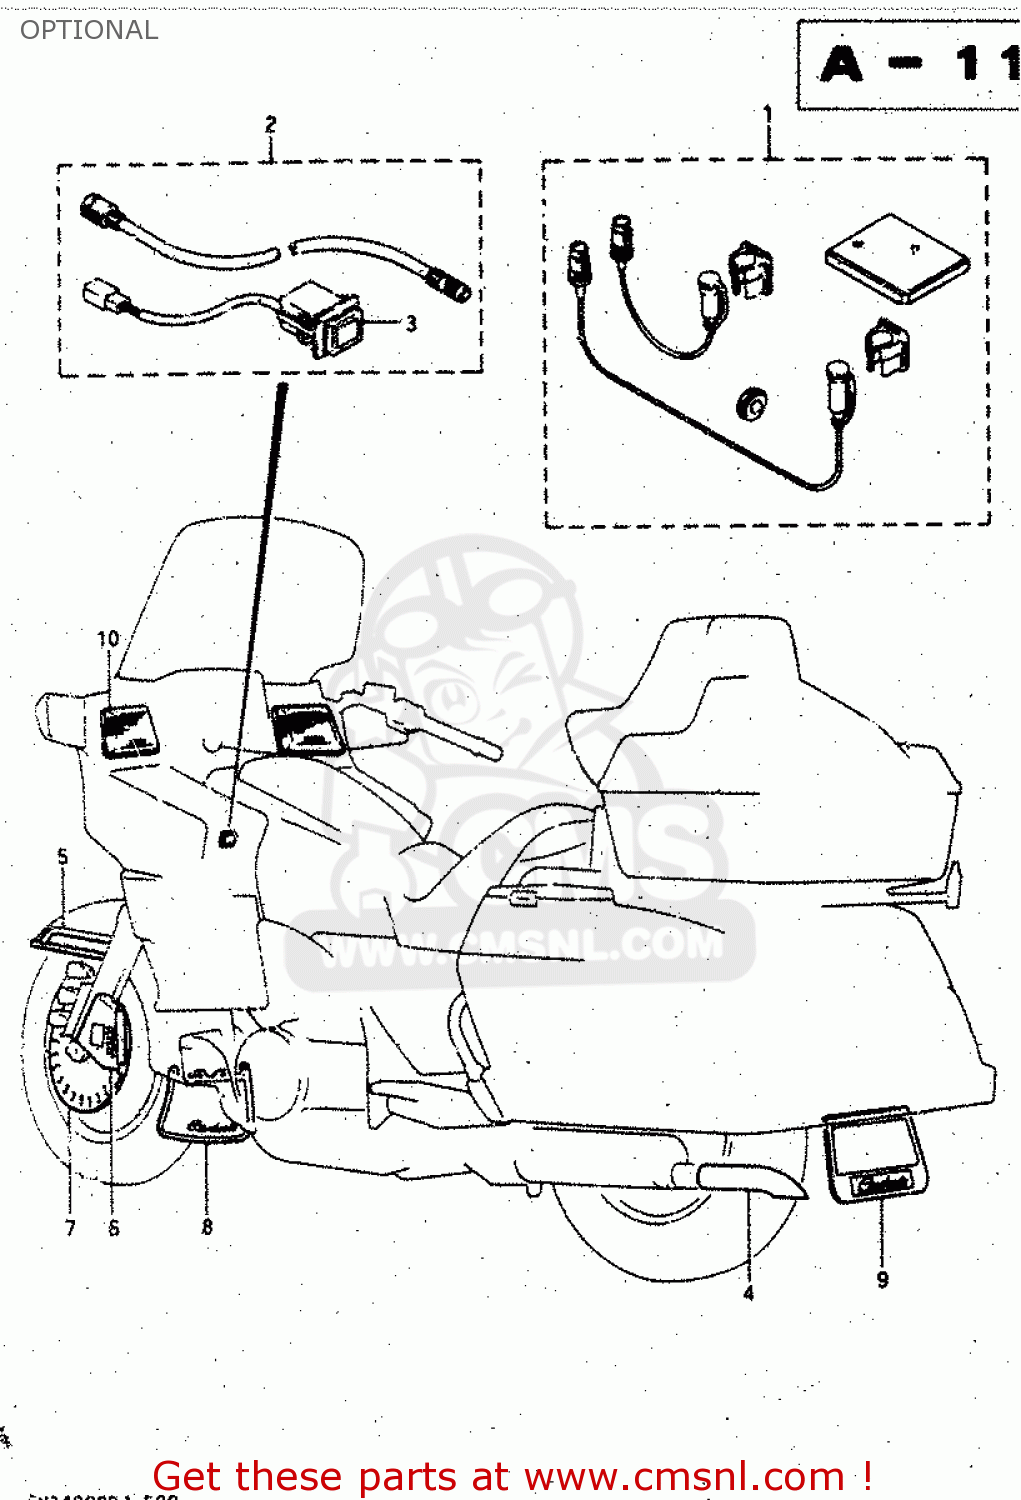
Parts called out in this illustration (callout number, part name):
1	HEAD SET,JUNCTION LEAD
2	AUXILIARY AIR HOSE SET
3	SWITCH ASSEMBLY,AIR AUXILIARY
4	EXHAUST EXTENSION
5	FRONT FENDER TRIM
6	FRONT CALIPER COVER SET
7	COVER,FRONT DISC,RIGHT
8	GUARD,MUFFLER,FRONT
9	MUD GUARD,REAR FENDER
10	GRILLE SET,SPEAKER
